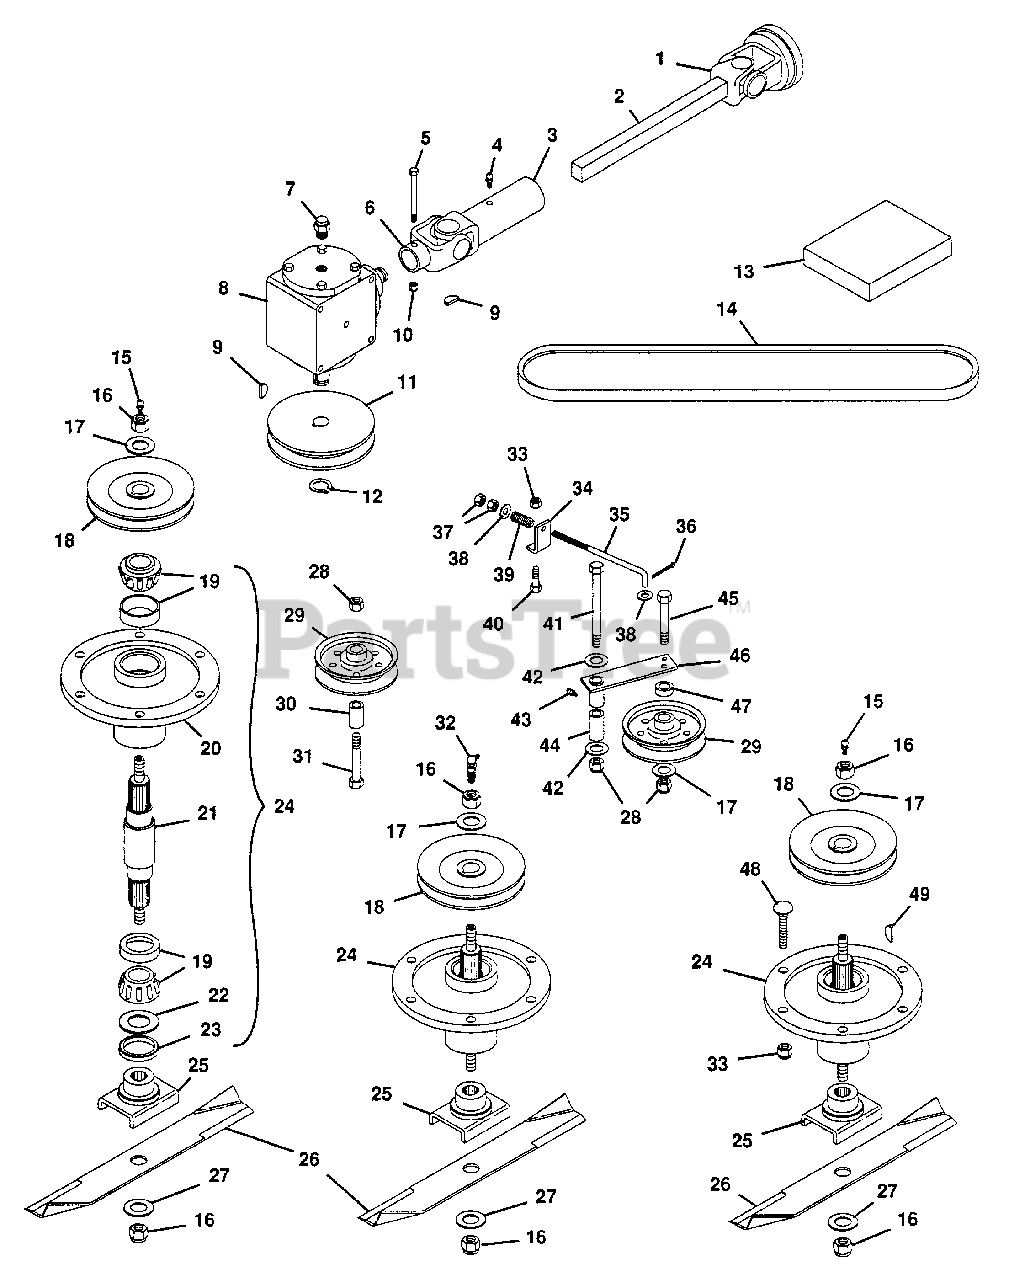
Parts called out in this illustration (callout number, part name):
1	Yoke
2	Assembly, Male U-Joint
3	Assembly, Female U-Joint
4	Fitting, Lube 1/4-28
5	Bolt, Hex 5/16-18x2.25
6	Yoke
7	Plug, 1/8 Vent
8	Gearbox, 72" Mower
9	Key, Woodruff .250x.875 HRD #A
10	Nut, Lock 5/16-18
11	Sheave, Gearbox
12	Ring, Retaining .875 Shaft
13	Kit, Repair U-Joint
14	Belt, Vee 60" Mower
15	Fitting, Lube 1/8
16	Nut, Lock 5/8-11
17	Washer, Flat .687x1.312x.122
18	Weldment, Spindle Sheave
19	Assembly, Bearing
20	Housing, Bearing
21	Shaft, Spindle
22	Washer, Flat .975x1.970x.030
23	Seal, Steel
24	Assembly, Spindle
25	Weldment, Blade Cradle
26	Blade
27	Washer, Flat .656x1.312x.095
28	Nut, Lock 1/2-13
29	Pulley, Flat Idler
30	Bush., St. .562x.975x1.00 Stl.
31	Bolt, Hex 1/2-13x2.75
32	Fitting, Lube 65 Degree
33	Nut, Lock 3/8-16
34	Support, Spring ÒB"
35	Rod, Idler
36	Pin, Cotter .094x.75
37	Nut, Hex 3/8-24
38	Washer, Flat .406x.812x.065
39	Spring, Comp. 1x.78x338 Lb/N
40	Bolt, Hex 3/8-16x1.00
41	Bolt, Hex 1/2-13x3.75
42	Washer, Flat .500x1.250x.083
43	Fitting, Lube 1/4-28
44	Bush., St. .505x.855x2.50 Stl.
45	Bolt, Hex 1/2-13x2.00
46	Weldment, Idler Pivot
47	Bush., St. .516x.875x.300 Stl.
48	Bolt, 3/8-16x1.375 Rd Hd Sq Nk
49	Key, Woodruff .25x1.00 Hard #15
